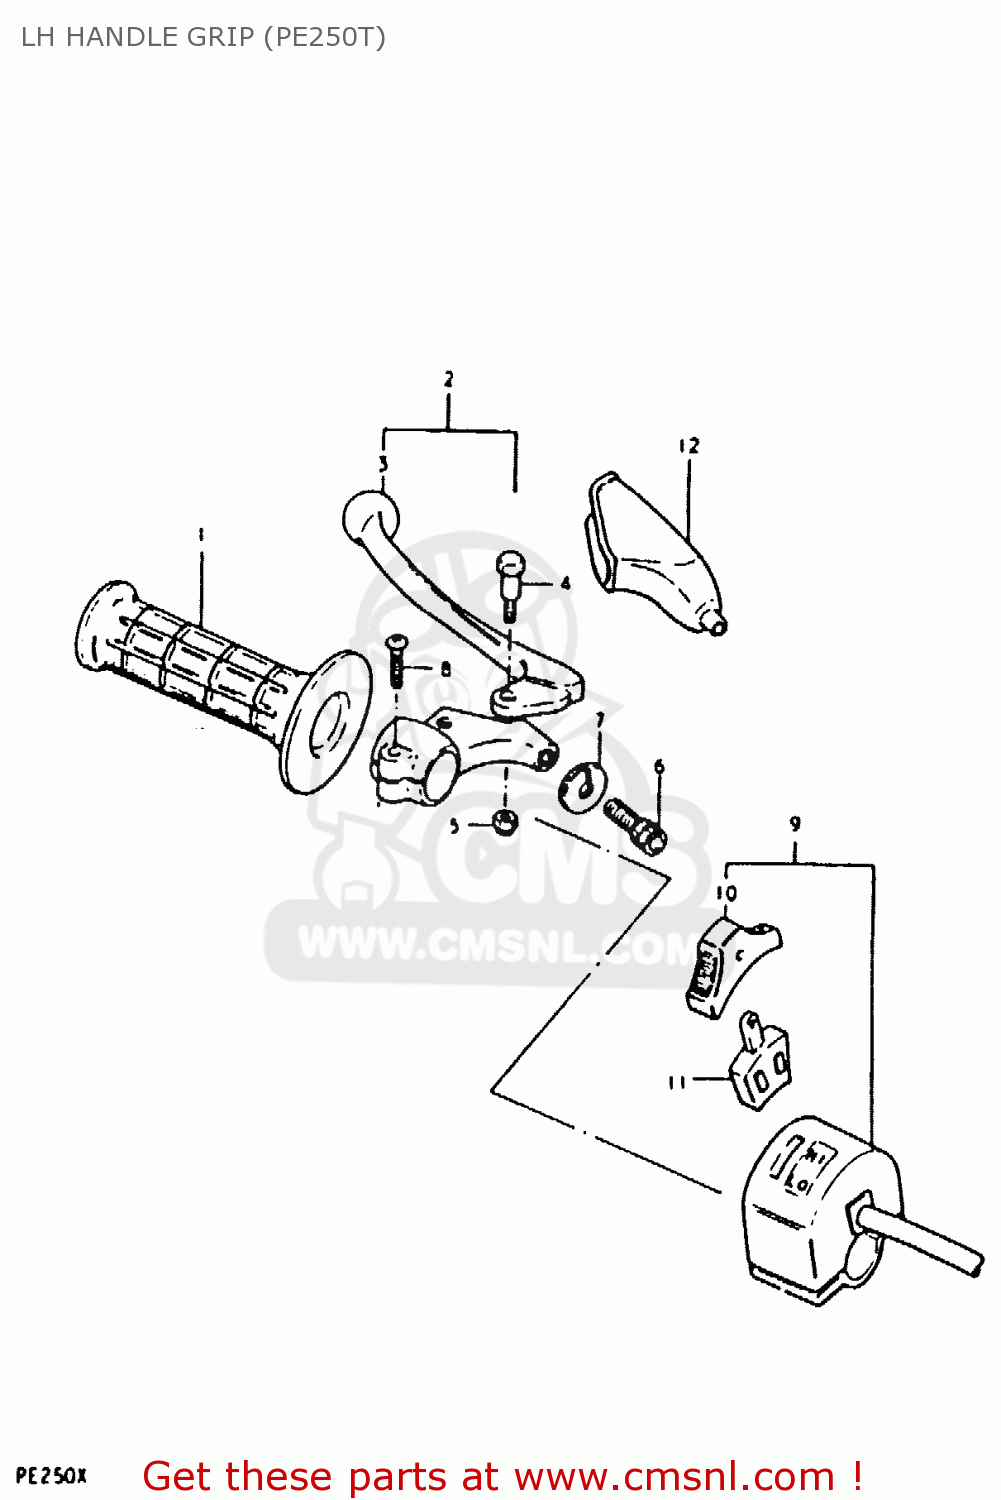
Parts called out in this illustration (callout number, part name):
1	GRIP,LEFT
2	LEVER ASSY,CLUTCH
3	LEVER,CLUTCH
4	BOLT,LEVER
5	NUT 6MM
6	ADJUSTER,CABLE
7	NUT,CABLE ADJUSTER
8	SCREW
9	SWITCH,DIMMER
10	KNOB,LIGHTING & DIMMER
11	BLOCK,LIGHTING/DIMMER
12	COVER,CLUTCH LEVER
